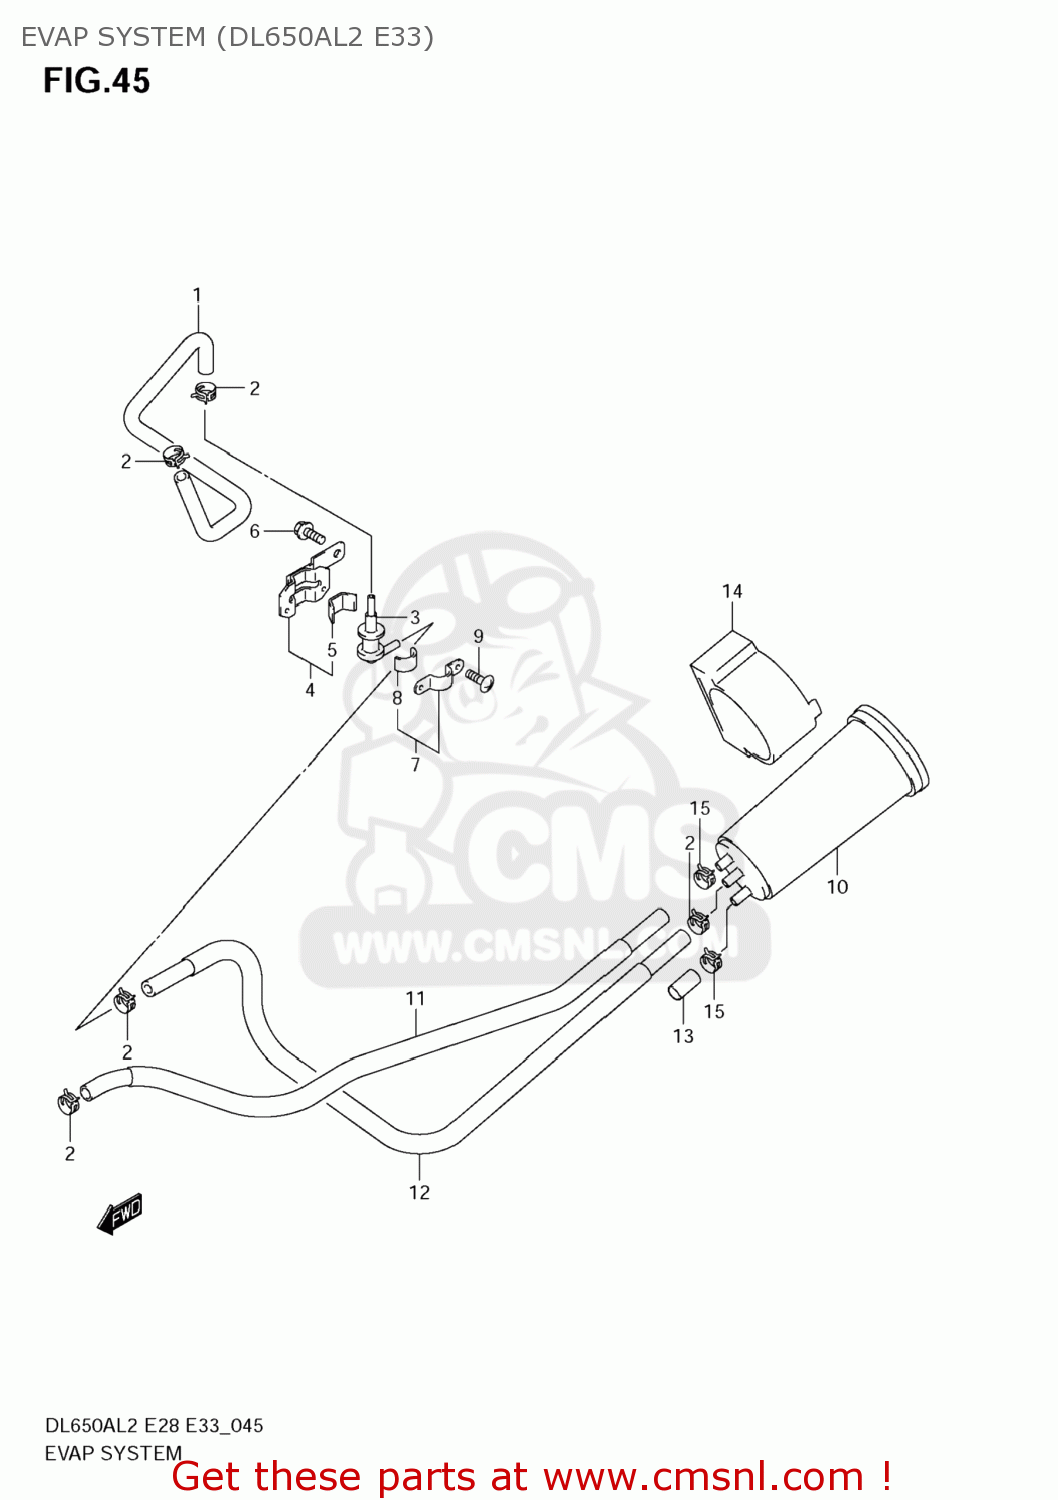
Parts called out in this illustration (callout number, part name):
1	HOSE,TANK & BREATHER VALVE
2	CLIP
3	VALVE,FUEL TANK BREATHER
4	PLATE,BREATHER VALVE
5	CUSHION
6	BOLT
7	PLATE,FUEL TANK BREATHER NO.2
8	CUSHION
9	SCREW
10	CANISTER ASSY,CHARCOAL
11	HOSE,CSTR PURGE
12	HOSE,CSTR SURGE
13	CAP,OD:11.5
14	CUSHION,CANISTER
15	CLIP
